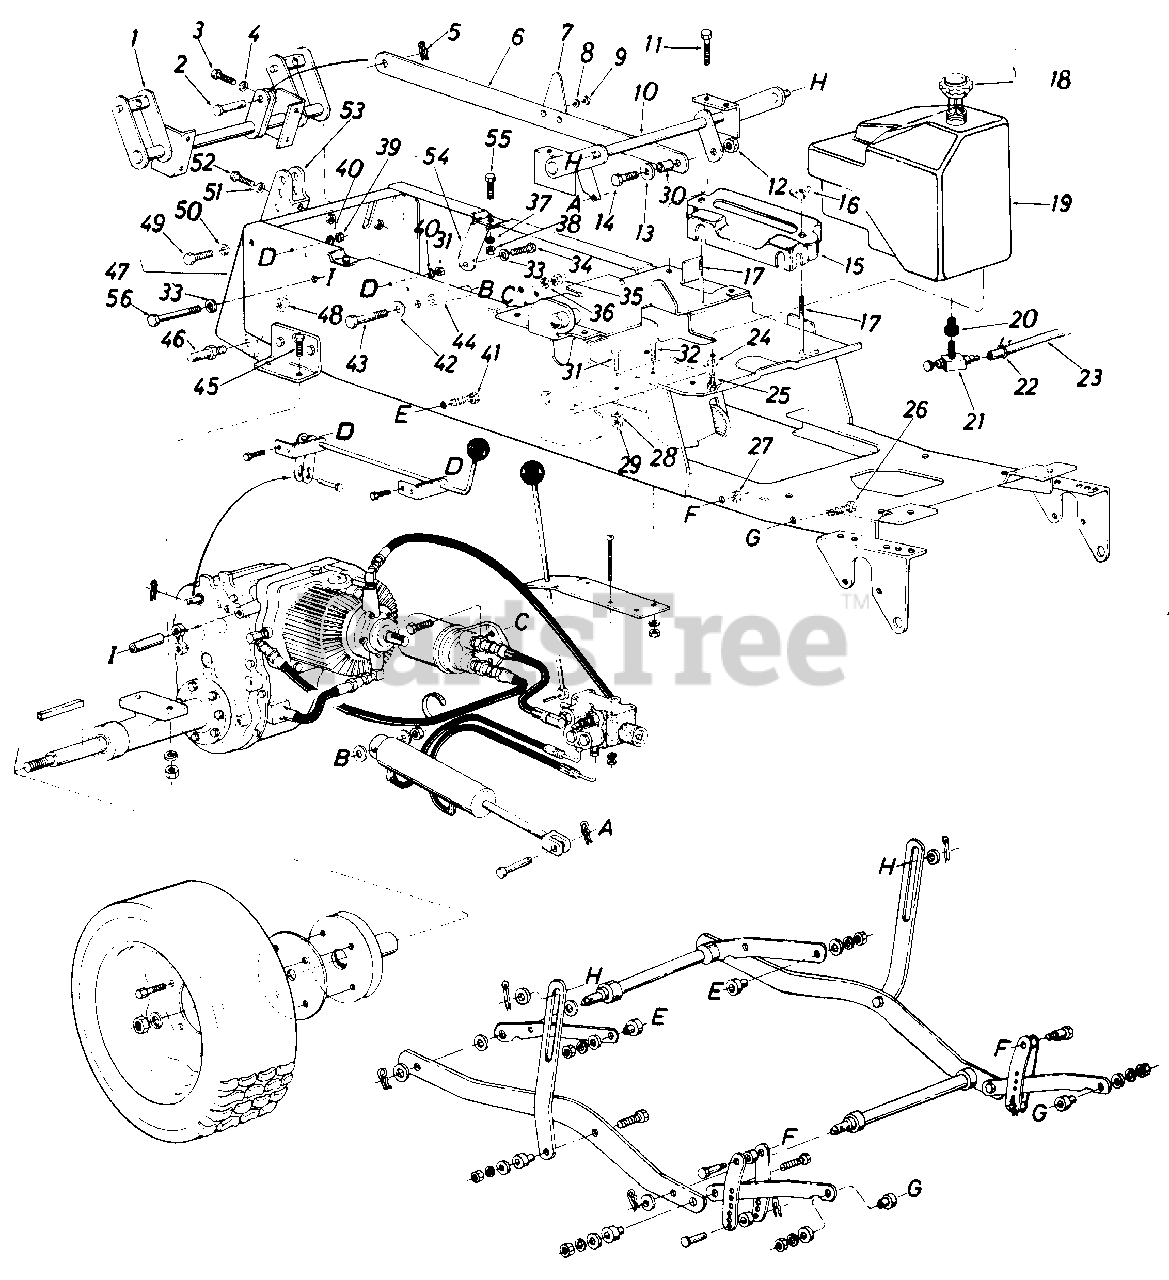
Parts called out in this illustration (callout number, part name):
1	Rear Lift Shaft Ass'y.
2	Clevis Pin
3	Hex Scr. 3/8-16 x 1.00" Lg. Grade 5
4	L-Wash. 3/8" Scr. H.D.
5	Cotter Pin 118" Dia. x 1.25" Lg.*
6	Push Bar Ass'y.
7	Position Indicator
8	L-Wash. 5/16" Scr.*
9	Hex Nut 5/16-18 Thd.*
12	Hex Cent. L-Nut 1/2-20 Thd.
13	Fl-Wash.
14	Hex Scr. 1/2-20 x 1.25" Lg.*
15	Battery Cover
16	Wing Nut 1/4-20 Thd.
17	Battery Hold Down Rods
18	Gas Tank Cap
19	Gas Tank Ass'y.
20	Bushing
21	Fuel Shut-Off Valve with Screen
22	Gas Line Clamp 7/16"
23	Gas Line 30" Lg.
24	Bell-Wash.
25	Hex Scr. 1/4-20 x .38" Lg.*
26	Hex Scr. 3/8-24 x 1.50" Lg.*
27	Hex Nut 3/8-16 Thd.*
28	L-Wash. 3/8" Scr.*
29	Hex Nut 3/8-16 Thd.*
30	Push Bar Sleeve
31	Hex Scr. 3/8-16 x 1.00 Lg. Grade 5
32	Hex Scr. 5/16-18 x .75" Lg.*
33	L-Wash. 1/2" Scr.*
34	Hex Scr. 1/2-13 x 1.25" Lg.*
35	Hex Nut 5/16-18 Thd.*
36	L-Wash. 5/16" Scr.*
37	L-Wash. 3/8" Scr. H.D.
38	Hex Nut 3/8-16 Thd.*
39	Hex Nut 1/4-20 Thd.*
40	L-Wash. 1/4" Scr.*
41	Hex Scr. 3/8-24 x 1.50" Lg.*
42	Fl-Wash. .50" I.D. x 1.25 O.D.
43	Hex Scr. 1/2-20 x 31/2 Lg. Grade 5
44	Spacer for Cylinder
45	Hex Scr. 3/8-16 x 1.75" Lg.*
46	Link Clevis Pin
47	Hitch Plate Ass'y.
48	Hex Cent. L-Nut 5/8-18 Thd.
49	Hex Scr. 3/8-16 x .75" Lg. Grade 5
50	L-Wash. 3/8" Scr.
51	L-Wash. 3/8" Scr. H.D.
52	Hex Scr. 3/8-16 x .75" Lg. Grade 5
53	Hitch Brkt.
54	Transmission Brace
55	Hex Scr. 3/8-16 x 1.00" Lg.*
56	Hex Scr. 1/2-13 x 2.75" Lg.*
